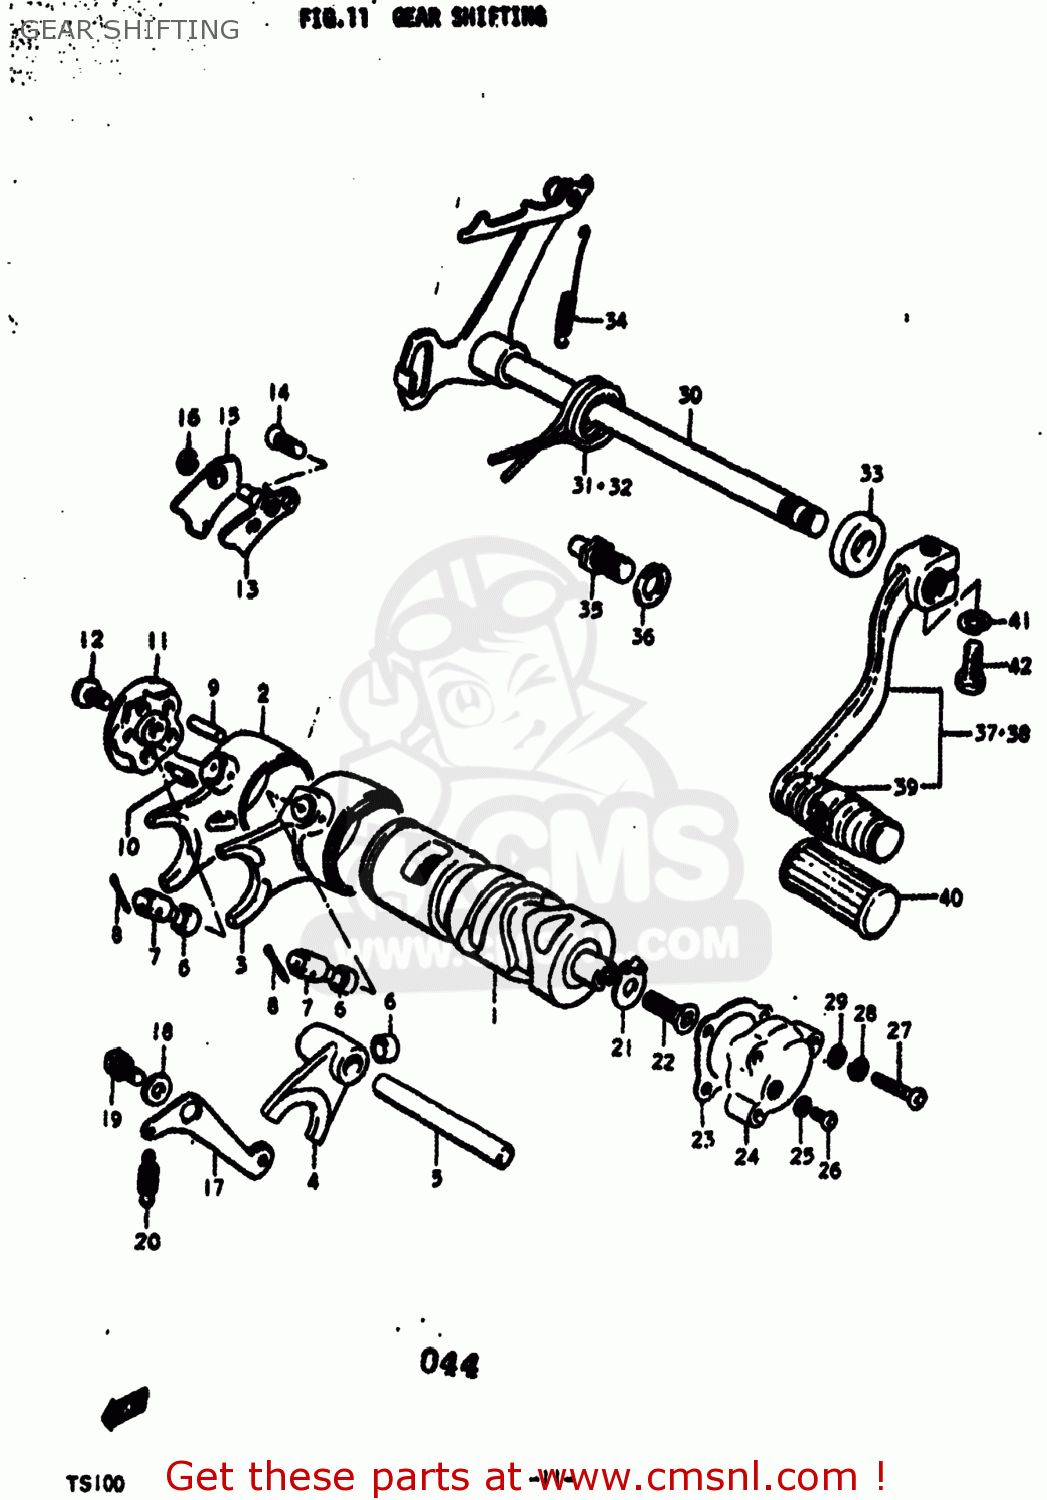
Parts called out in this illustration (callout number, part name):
1	CAM,GEAR SHIFT
2	FORK,GEAR SHIFT NO.1
3	FORK,GEAR SHIFT NO.2
4	FORK,GEAR SHIFT NO.3
5	SHAFT,GEAR SHIFT FORK
6	SPACER
7	PIN
8	PIN 25X20
9	PIN(4X20)
10	PIN
11	PLATE,GEAR SHIFT CAM STOPPER
12	SCREW
13	GUIDE,GEAR SHIFT CAM
14	SCREW
15	PAWL,GEAR SHIFTING CAM
16	E RING
17	STOPPER,GEAR SHIFTING
18	WASHER(6.5X16X2.3)
19	BOLT(6X16.1)
20	SPRING
21	CONTACT,GEAR SHIFT SWITCH
22	SCREW
23	GASKET,GEAR SHIFT SWITCH (NAS)
24	SWITCH,NEUTRAL INDICATOR
25	WASHER
26	SCREW
27	SCREW
28	LOCK WASHER
29	WASHER
30	SHAFT,GEAR SHIFT
31	SPRING
32	SPRING
33	OIL SEAL
34	SPRING
35	STOPPER,GEAR SHIFT ARM
36	LOCK WASHER
37	LEVER ASSY,GEAR SHIFT
38	LEVER ASSEMBLY,GEAR SHIFTING
39	RUBBER,GEAR SHIFT PEDAL
40	RUBBER,GEAR SHIFT PEDAL
41	LOCK WASHER
42	BOLT
